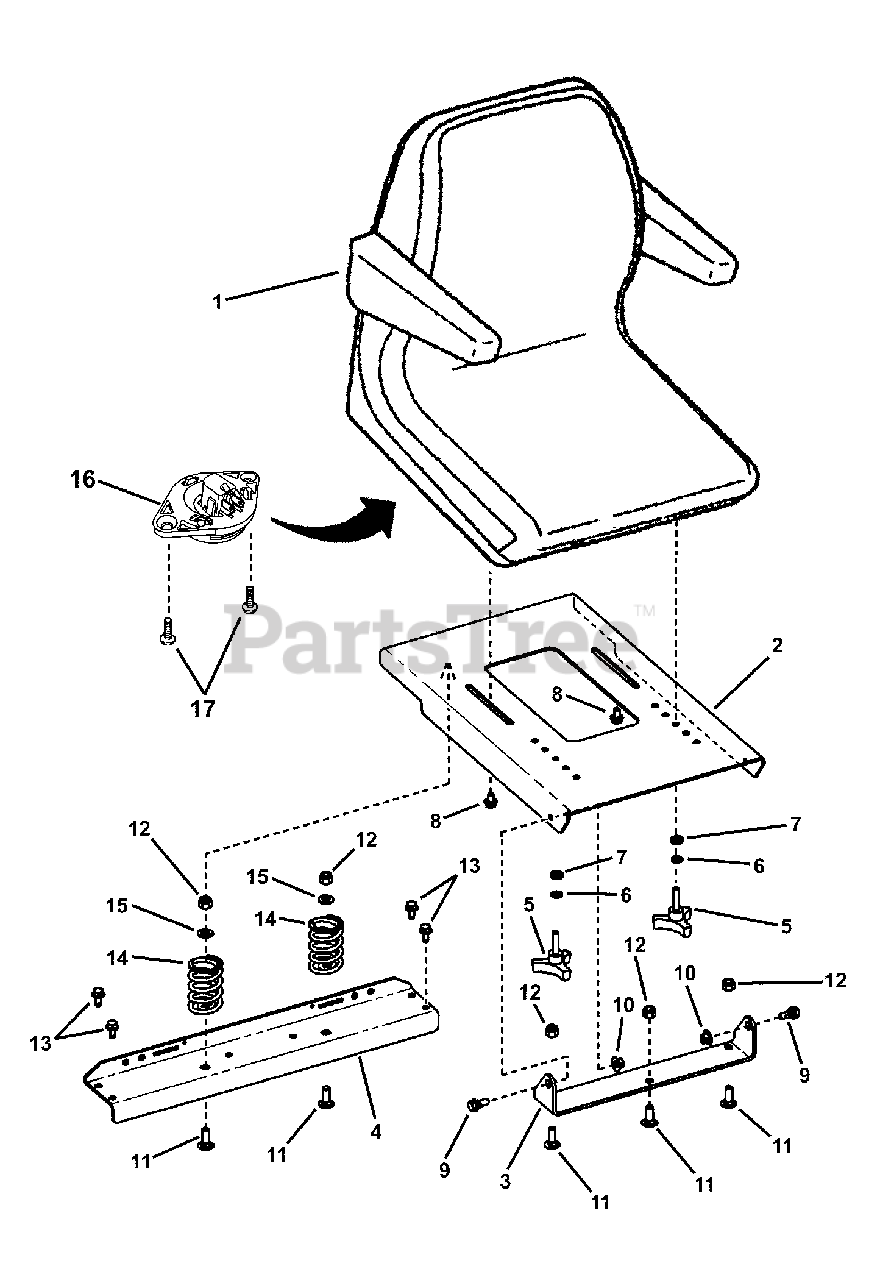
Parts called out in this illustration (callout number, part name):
1	* SEAT (Milsco) w/ Urban Gray Vinyl
2	SEAT PLATE
3	PIVOT BRACKET, Seat Hinge
4	CROSS PLATE
5	KNOB, Three Prong (5/16-18)
6	WASHER, 5/16" Split Lock
7	SPACER, .33 x .63 x .156
8	SCREW, 5/16-18 x 1/2" Hex Washer Machine
9	SHOULDER BOLT, 5/16-18
10	NUT, 5/16-18 Large Flange Hex Center Lock
11	BOLT, 3/8-16 x 1" Square Neck Carriage, GR 5
12	NUT, 3/8-16 HEX NYLON LOCK
13	SCREW, 5/16-18 x 5/8" Hex Washer Self-Tap
14	SPRING, Compression- Seat Support
15	WASHER, 3/8" SAE Flat
16	ASSEMBLY, Seat Switch (NC)
17	SCREW, HEX WSHR HD PLAST .250 X .500 BLK
